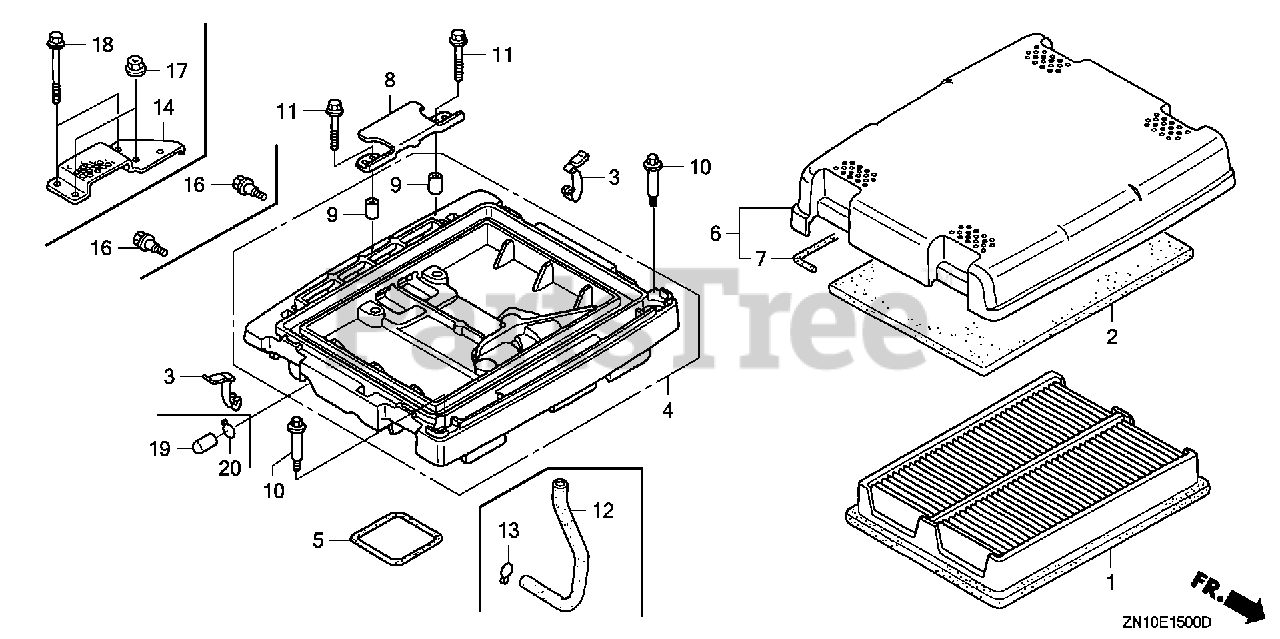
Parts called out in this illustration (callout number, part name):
1	ELEMENT ASSY., AIR CLEANER
2	FILTER (OUTER)
3	CLIP, AIR CLEANER
4	HOUSING, AIR CLEANER
6	COVER ASSY., AIR CLEANER
7	SEAL, AIR CLEANER COVER
9	COLLAR A, AIR CLEANER
10	BOLT, SPECIAL (5MM)
12	TUBE, BREATHER
13	CLIP, BREATHER TUBE
14	CAP, AIR CLEANER
16	BOLT, FLANGE (6MM)
17	NUT, FLANGE (6MM)
18	BOLT, FLANGE (6X95)
